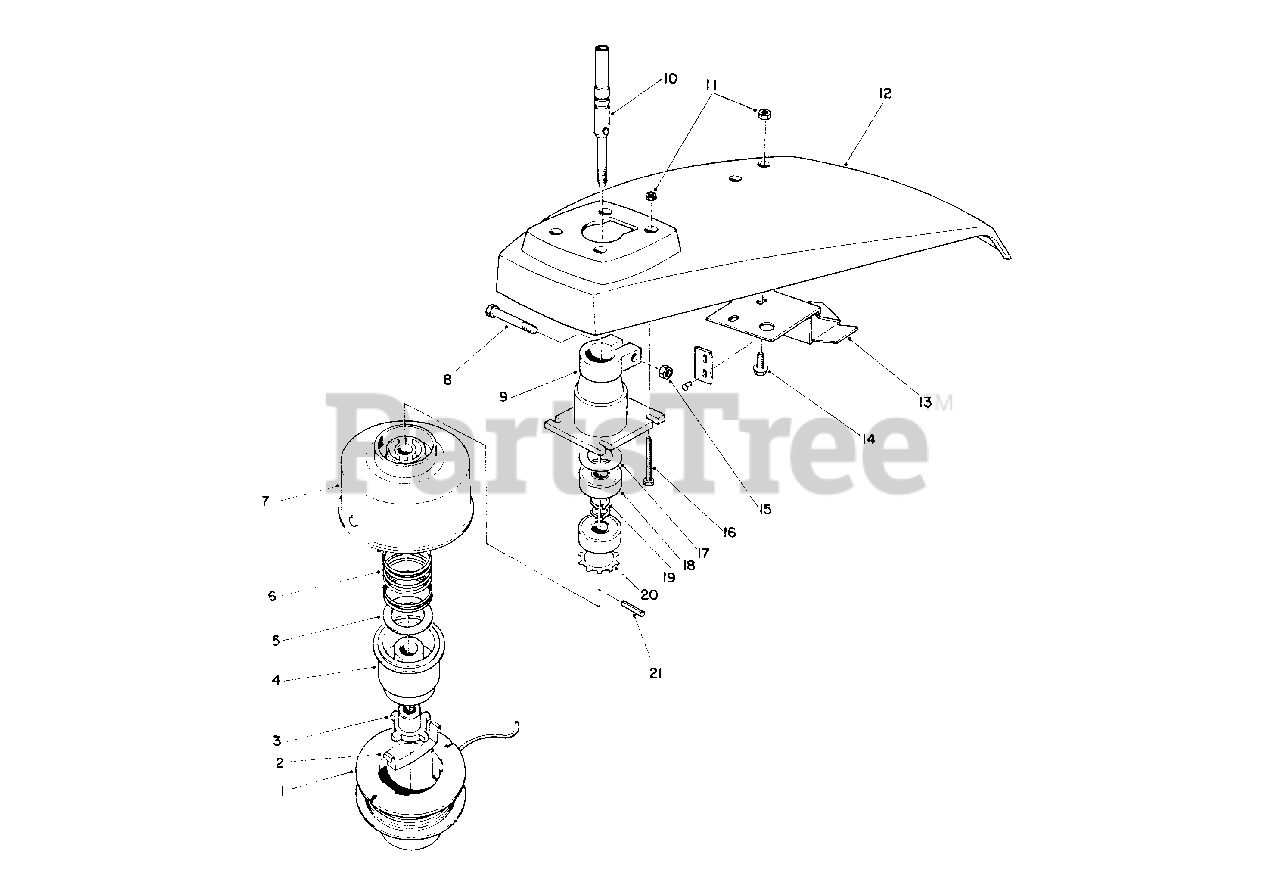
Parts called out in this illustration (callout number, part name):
1	Spool & Line Assembly
2	Saddle-Spool Cap
4	Spool Core
6	Spring-Compression
7	Drum & Eyelet Assembly
8	Hex Hd. Capscrew
9	Housing-Bearing (Incl. Ref. #10, 17-21)
10	Shaft-Power
11	Locknut
13	Bracket & Knife Blade
14	Hex Washer Hd. Mach. Screw
16	Hex Hd. Machine Screw
17	Washer
18	Ball Bearing
19	Snap Ring
20	Grip-Spring
21	Coil Pin
